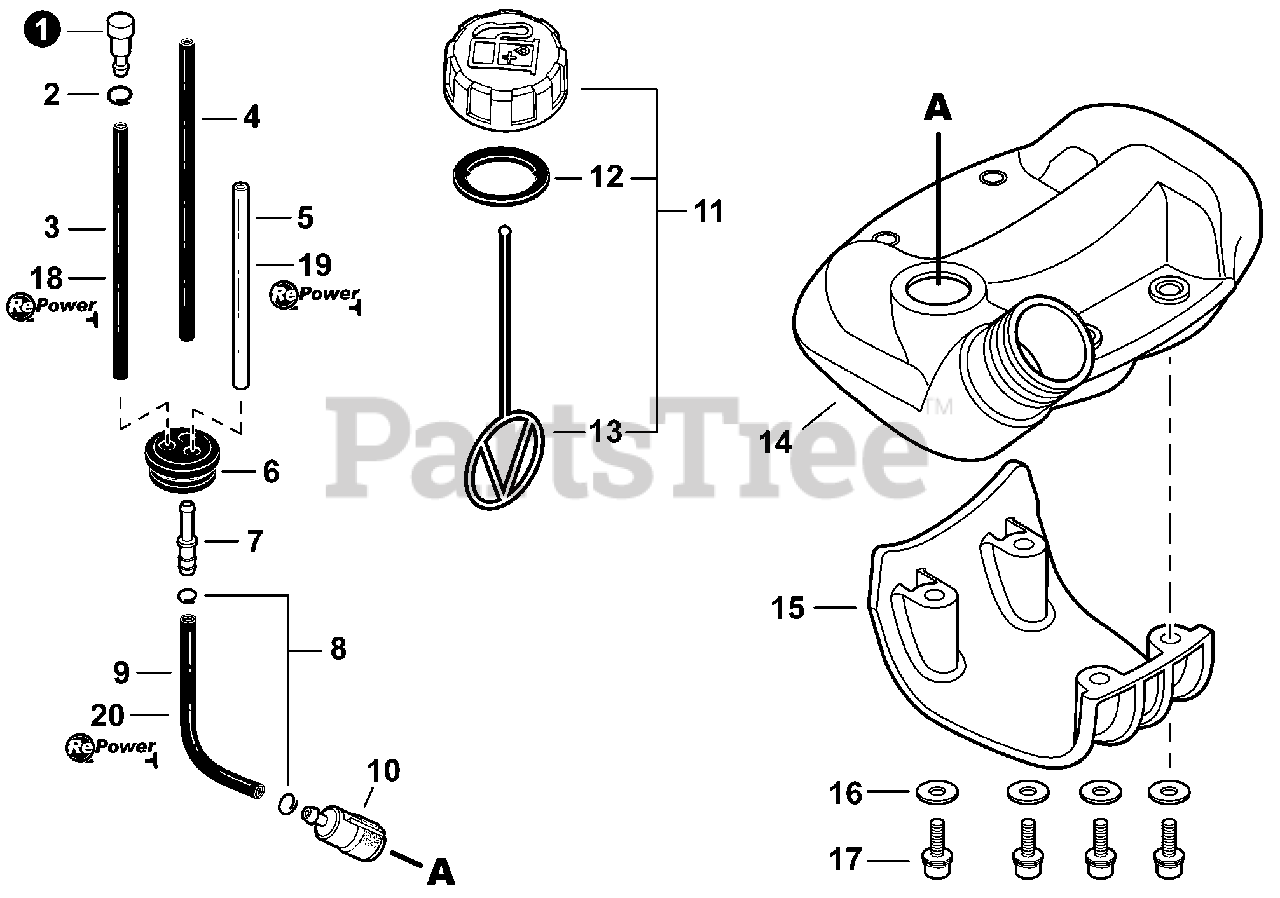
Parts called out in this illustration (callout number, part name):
1	VENT ASSY
2	CLIP 6.5 MM
3	PIPE, FUEL 3x6x35 BLACK
4	PIPE, FUEL - 3x5x67 - BLACK
5	PIPE, FUEL 3x6x75 CLEAR
6	GROMMET, FUEL
7	CONNECTOR, PIPE 5x3.5
9	PIPE, FUEL - 3x5x125 - BLACK
10	FILTER, FUEL
11	CAP ASSY, FUEL
12	GASKET, FUEL CAP
13	CONNECTOR, CAP L= 100 MM
14	TANK, FUEL
15	GUARD, FUEL TANK
16	WASHER 5.5x12x0.8
17	BOLT 5x25
18	BULK PIPE - 3x6 MM BLACK (4 PIECESx2 M)
19	BULK PIPE - 3x6 MM CLEAR (4 PIECESx2 M)
20	BULK PIPE - 3x5 MM BLACK (4 PIECESx2 M)
